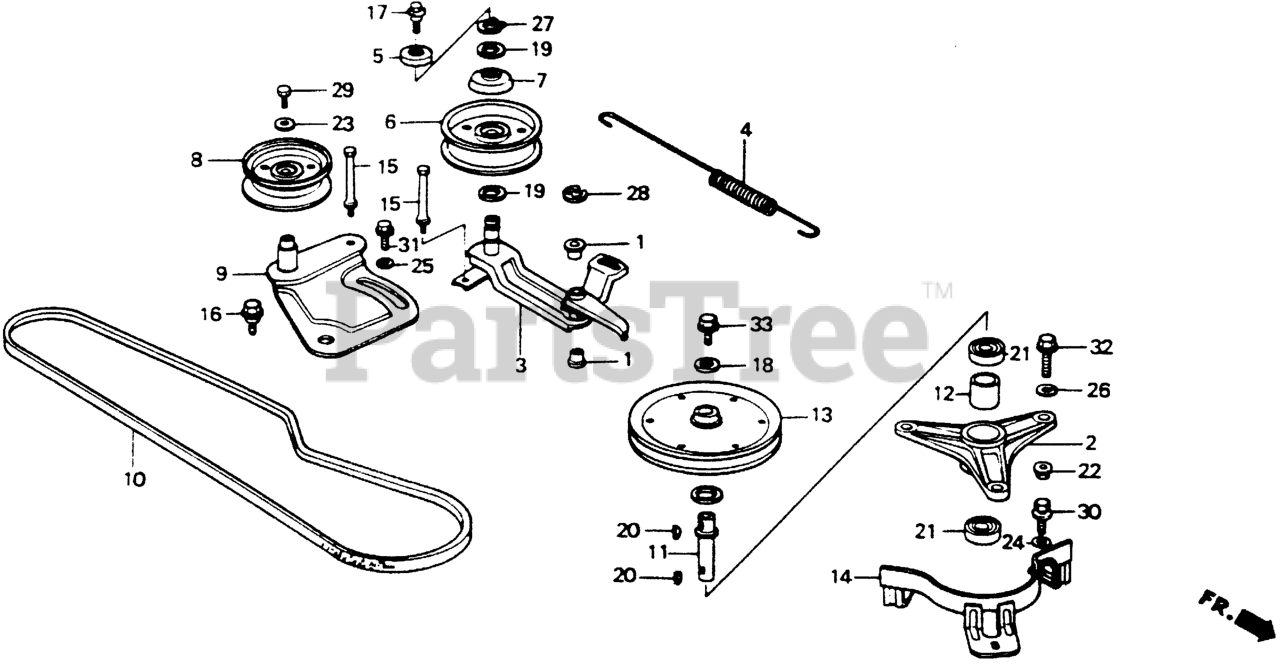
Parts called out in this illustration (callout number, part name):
1	BUSH (15X19X22)
2	HOUSING, BEARING
3	ARM, TENSION (DECK) (NOT AVAILABLE)
4	SPRING, TENSIONER ARM
5	GRIP, TENSION ARM (NOT AVAILABLE)
6	ROLLER, TENSIONER
7	DUST COVER, TENSION PULLEY (NOT AVAILABLE)
8	PULLEY, TENSIONER
9	ARM, BELT ADJUSTING
10	V-BELT, BLADE (SB-70)
11	SHAFT, BLADE
11	SHAFT, BLADE (112.5MM)
12	COLLAR, BLADE SHAFT
13	PULLEY, CUTTER DECK (120MM)
14	COVER, DECK PULLEY
15	BOLT, BELT STOPPER
16	BOLT, ADJUSTING ARM
17	BOLT, FLANGE (6MM)
18	WASHER (10.3MM)
19	WASHER (17.3X25)
21	BEARING, RADIAL BALL (6204UU)
23	WASHER, PLAIN (6MM)
24	WASHER, PLAIN (6MM)
25	WASHER, PLAIN (8MM)
27	CIRCLIP (OUTER) (17MM)
28	E-RING (12MM)
29	BOLT, FLANGE (6X12) Use up to Engine SN 1543277.
30	BOLT, FLANGE (6X16)
31	BOLT, FLANGE (8X16) Use from Engine SN 1000016.
32	BOLT, FLANGE (10X28)
33	BOLT, FLANGE (10X16)
